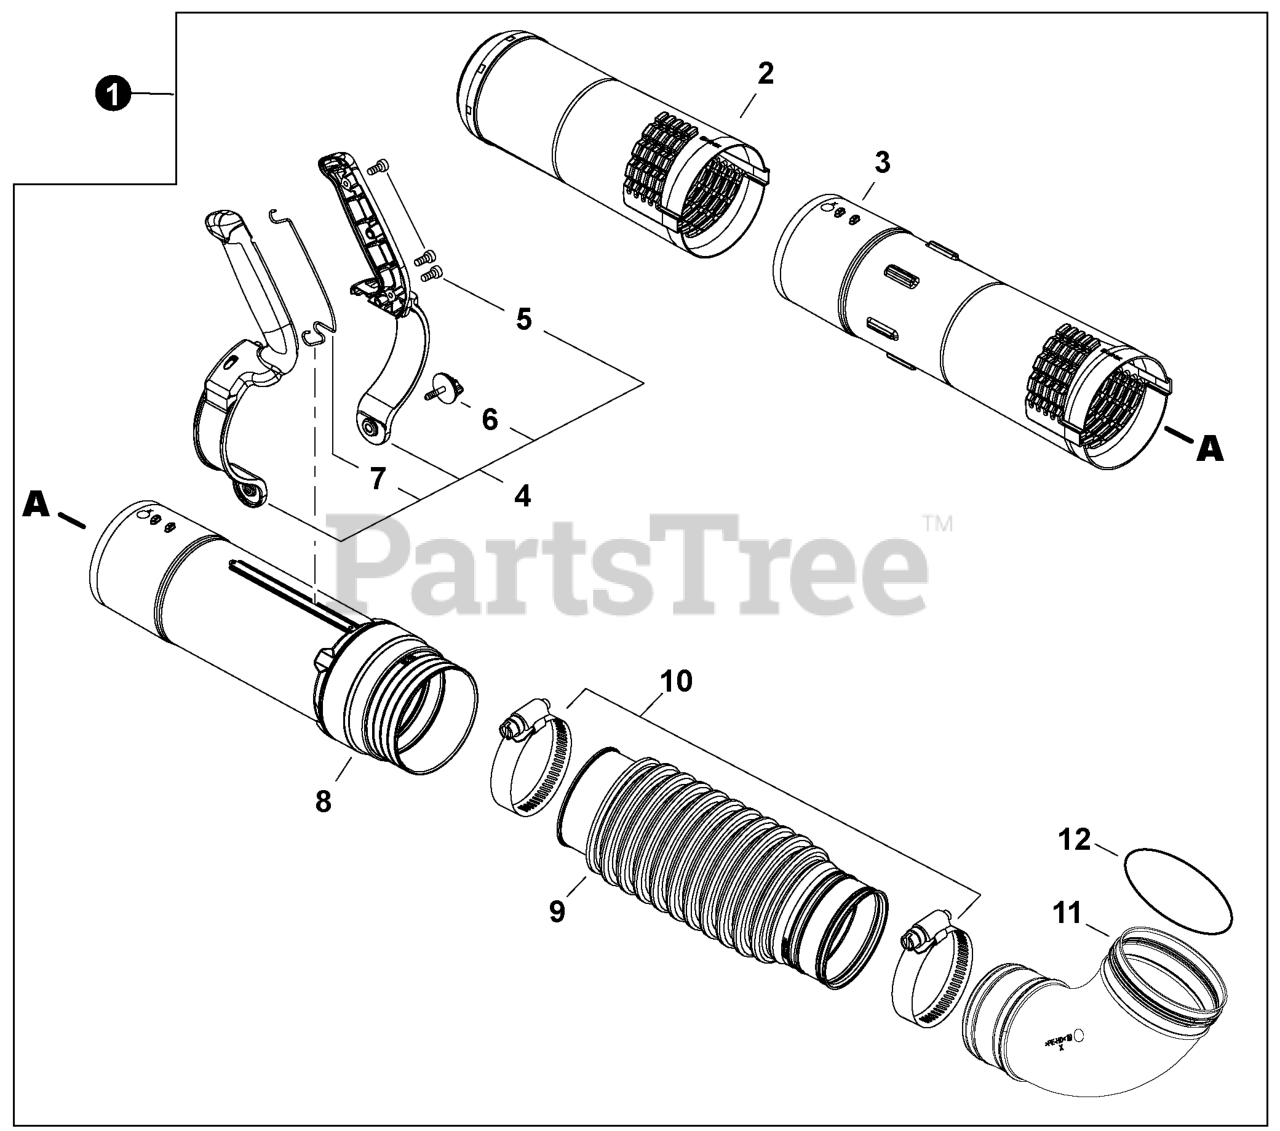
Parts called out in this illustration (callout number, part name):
1	TUBE KIT, BLOWER, HIP MOUNT
2	TUBE, BLOWER - NOZZLE
3	TUBE, BLOWER - STRAIGHT
4	HANDLE KIT - BLOWER TUBE
5	BOLT, TORX 4x12
6	KNOB, FASTENER
7	PLATE, GROUND
8	TUBE, BLOWER - SWIVEL
9	TUBE, BLOWER - FLEXIBLE
10	CLAMP - BAND
11	TUBE, BLOWER - ELBOW
